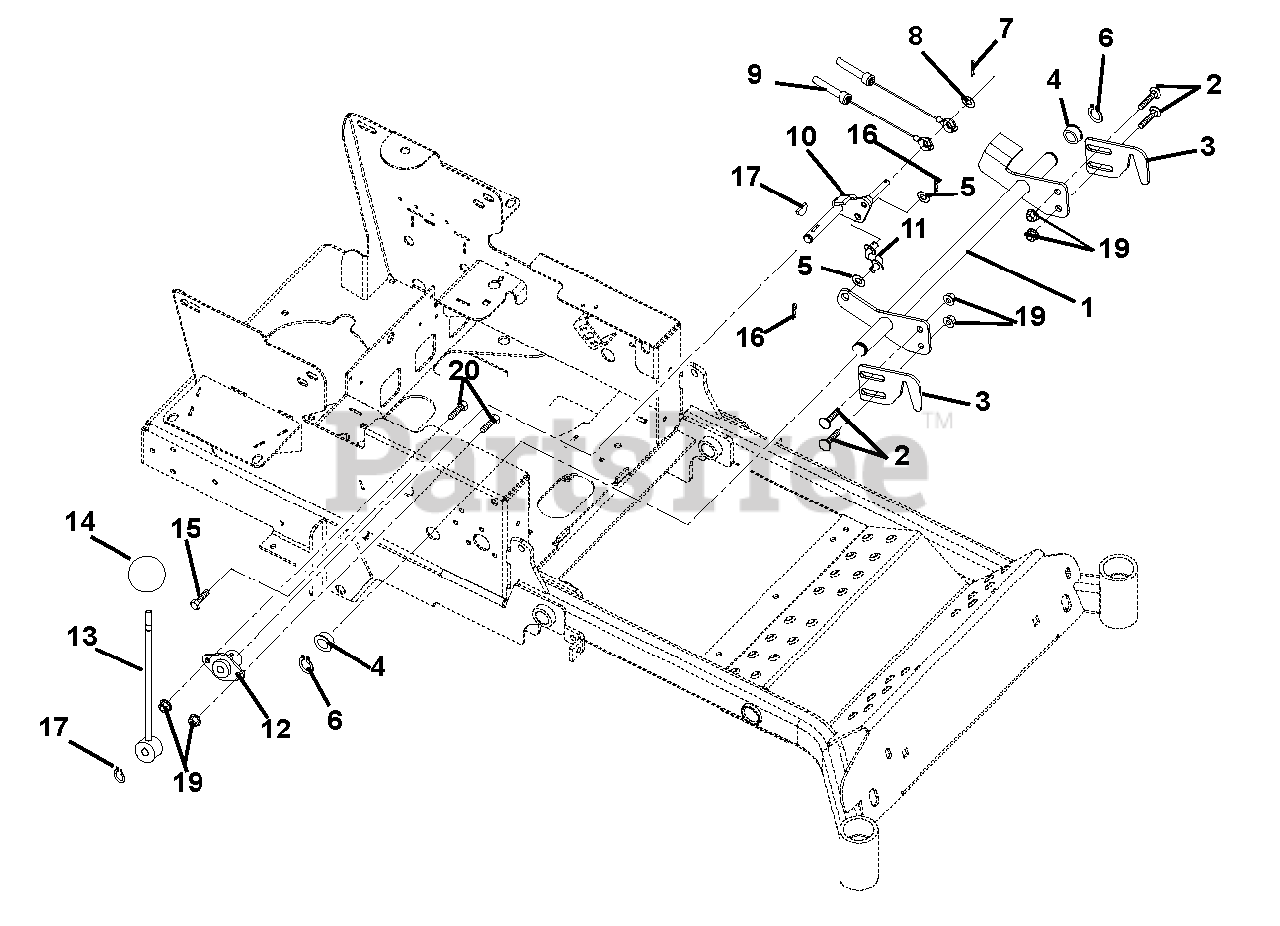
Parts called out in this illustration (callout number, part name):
1	Weldment, Neutral Lock Arm
2	Bolt, Round Head Square Neck .31-18 x 1.00 Grade 5
3	Neutral Lock Latch
4	Bushing, Flange .750 x 1.000 x .625 x 1.250
5	Washer, Flat Steel .406 x .812 x .065
6	Ring, Retaining-External .689 x .077
7	Pin, Hair-Internal .06 x .18 x .77
8	Washer, Flat-Steel .344 x .688 x .065
9	Cable, Brake Actuating
10	Weldment, Park Brake Arm
11	Link, Brake Interlock
12	Bushing, Flanged
13	Weldment, Parking Brake Lever
14	Knob, Ball-Black 1.47"
15	Screw, Tapping .38-16 x 1.00 Hex Washer Head
16	Pin, Hair
17	Key, Woodruff .13 x .63
18	Ring, Retaining External .50 x .05
19	Nut, Nyloc Flange 5/16-18
20	Bolt, Hex .31-18 x 1.00 Grade 5
